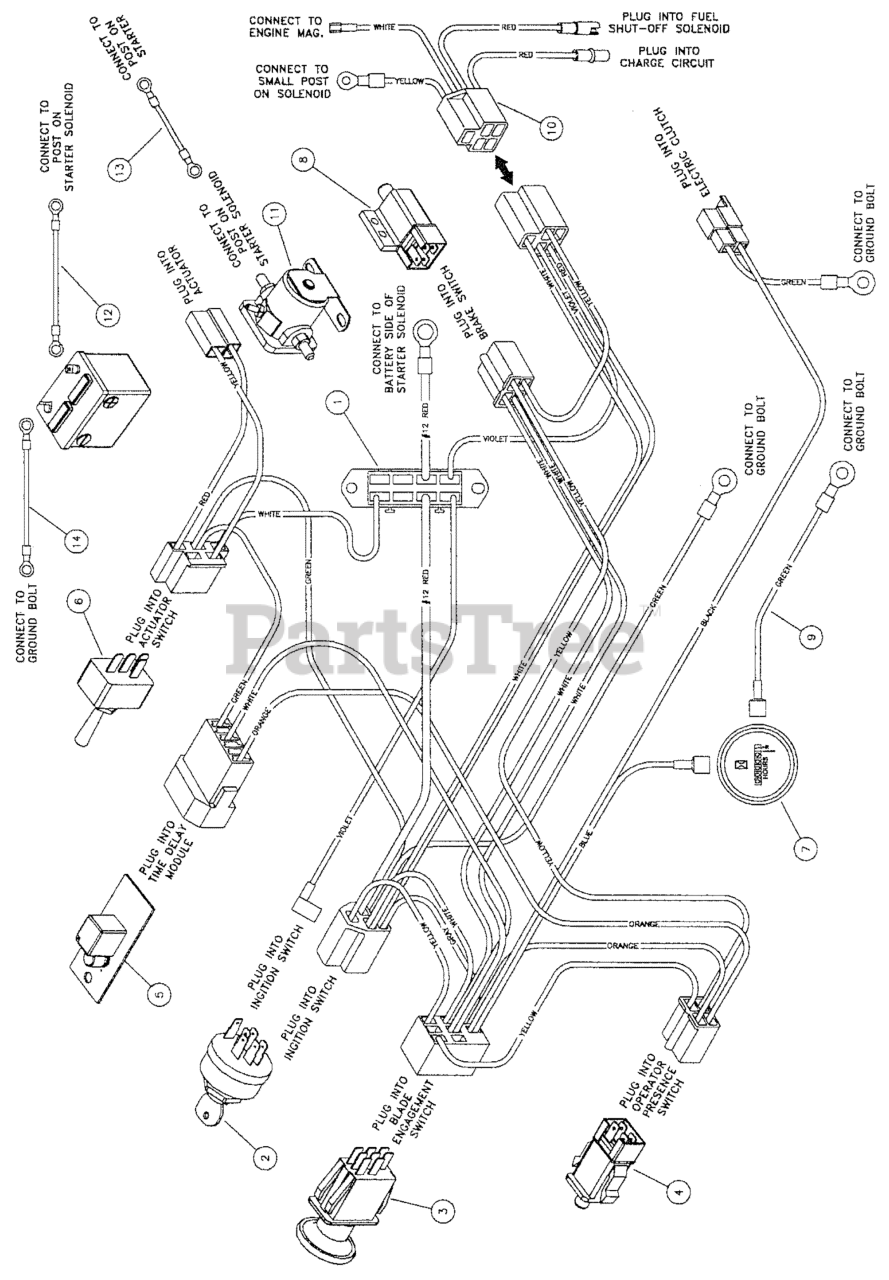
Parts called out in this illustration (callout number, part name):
1	3-Wheel Rider Wire Harness (includes #1545205)
2	SWITCH, IGNITION, 6 POST
3	SWITCH, BLADE ENGAGEMENT
4	Switch, Plunger Snap-In
5	Time Delay Module
6	Switch, Electric Actuator
7	Hour Meter
8	SWITCH, PLUNGER, N.O./N.C.
9	Hour Meter Ground Wire
10	Briggs Adapter Harness
11	Solenoid, Starter
12	Positive (+) Battery Cable
13	Starter Cable
14	BATTERY CABLE, NEG, 22, 1/4-5/16
